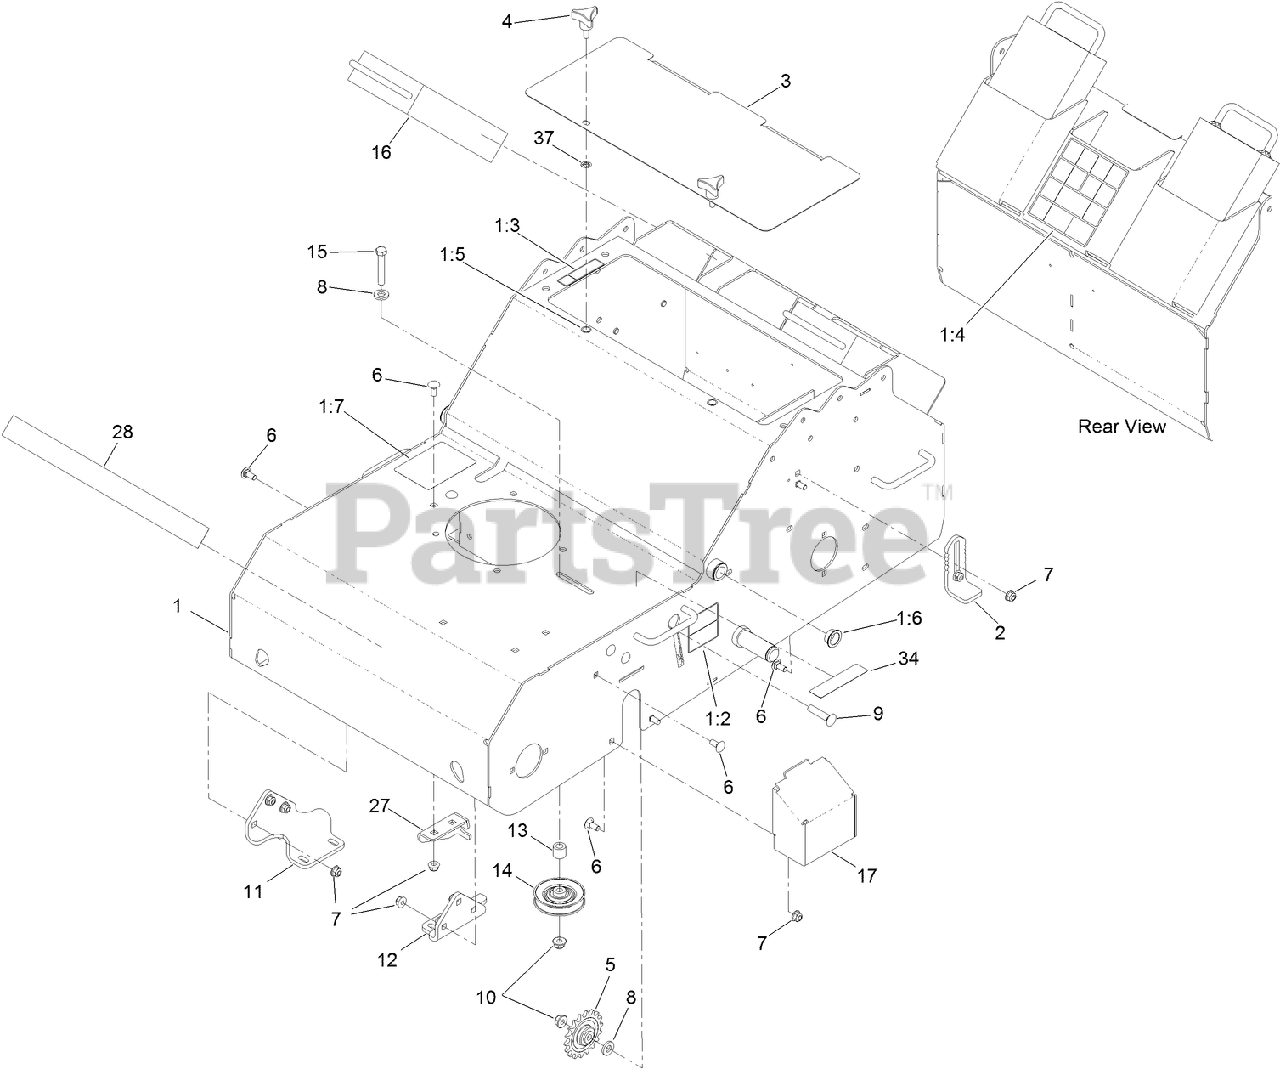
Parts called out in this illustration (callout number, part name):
1	FRAME ASM
1:2	DECAL-WARNING
1:3	DECAL-DANGER
1:4	DECAL-WARNING
1:5	NUT-INSERT
1:6	BUSHING-BRONZE
1:7	DECAL-SERVICE AID
2	STOP-DEPTH
3	COVER-ACCESS
5	SPROCKET-IDLER
6	BOLT-CARR
7	NUT-HF, NI
8	WASHER
9	SCREW-CARR
10	NUT-HF, NI
11	BRACKET-MOUNT AXLE, RH
12	BRACKET-MOUNT AXLE, LH
13	BUSHING-IDLER
14	PULLEY
15	SCREW-HH
16	WEIGHT-AERATOR
17	COVER-TRANSAXLE
27	BRACKET-MOUNTING, CABLE
34	DECAL-ARRESTER, SPARK
37	NUT-PUSH
